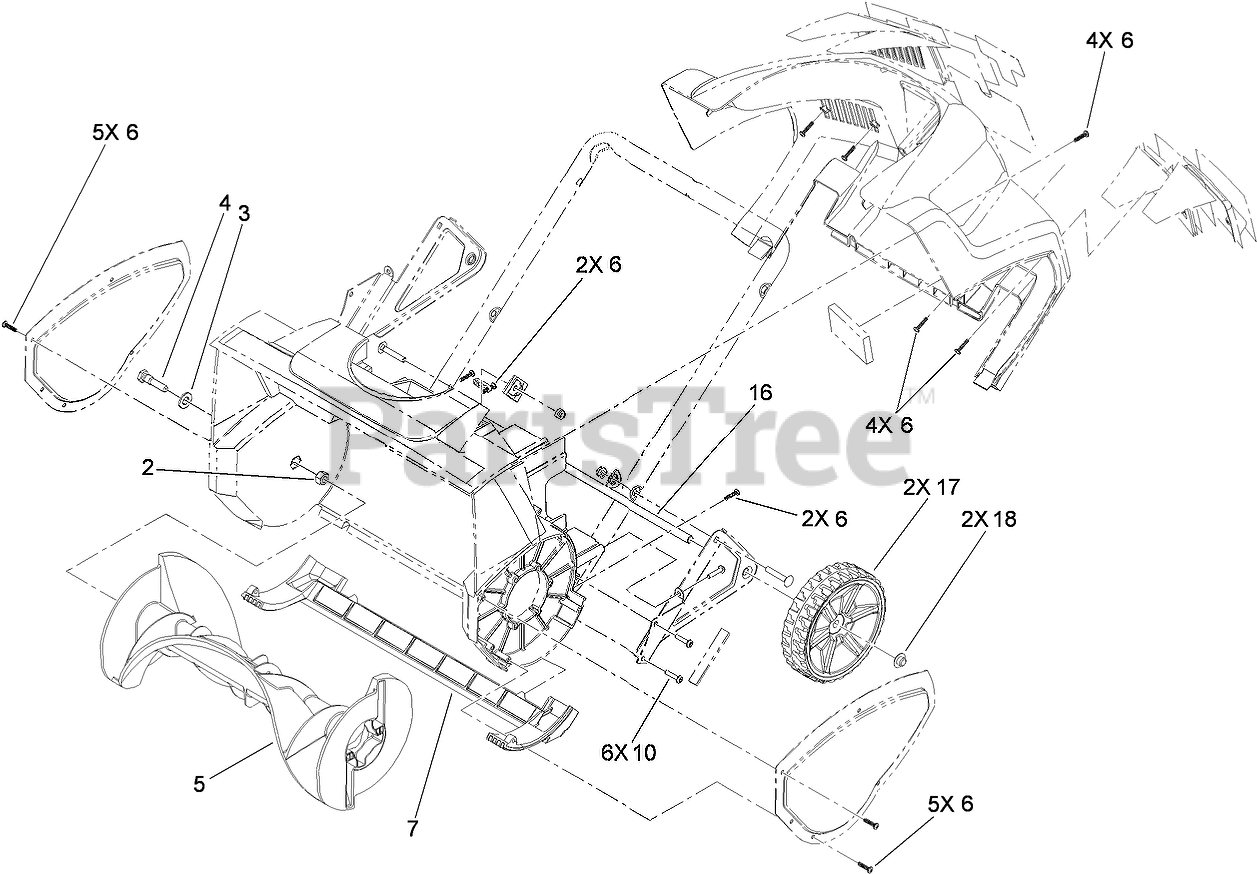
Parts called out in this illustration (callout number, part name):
2	NUT-LOCK
3	WASHER-FLAT
4	PIN-ROTOR
5	ROTOR ASM
6	SCREW-PPH
7	SCRAPER
10	SCREW-PPH
16	AXLE-WHEEL
17	WHEEL ASM
18	RETAINER-PUSH ON
